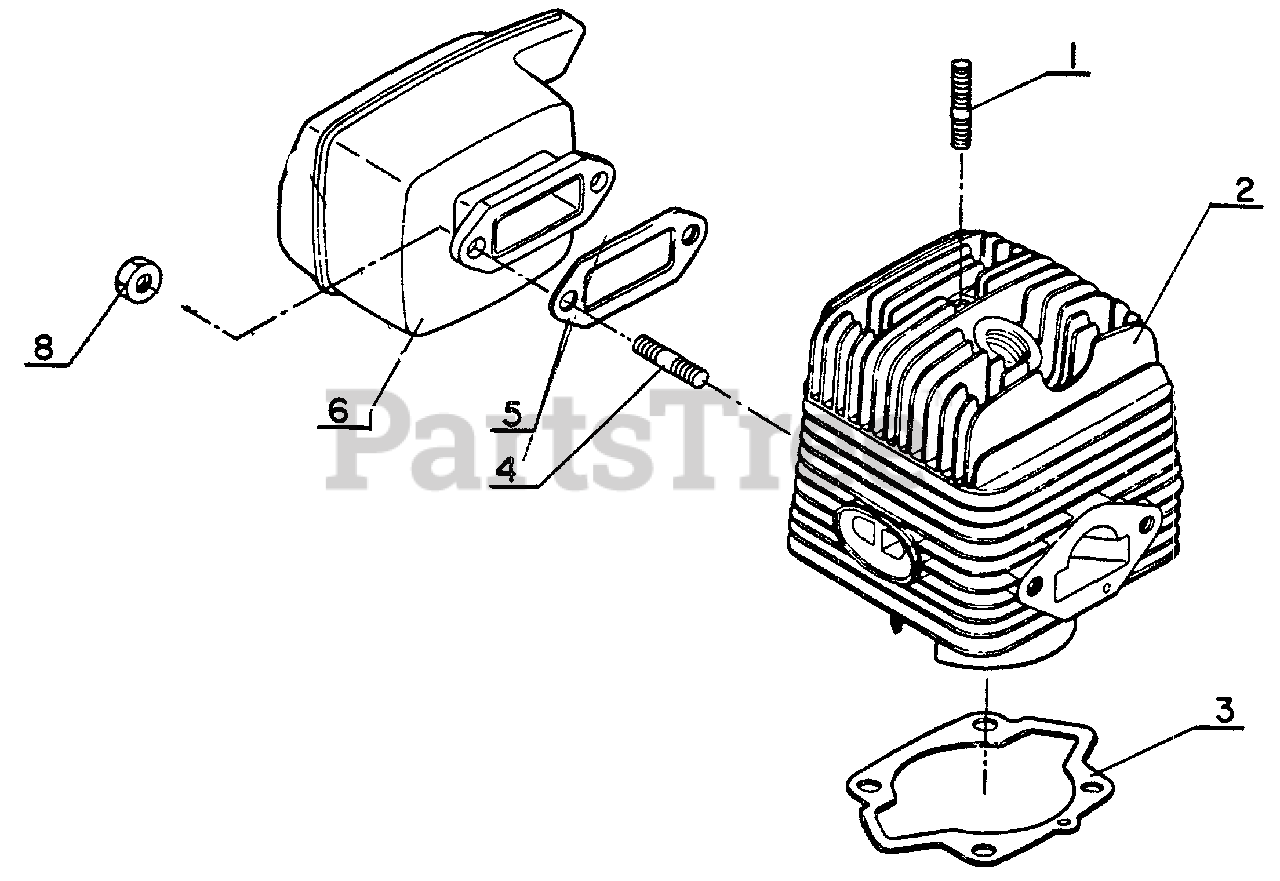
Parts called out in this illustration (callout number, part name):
2	CYLINDER
3	GASKET, CYLINDER
5	GASKET, EXHAUST
8	LOCKNUT - 6
